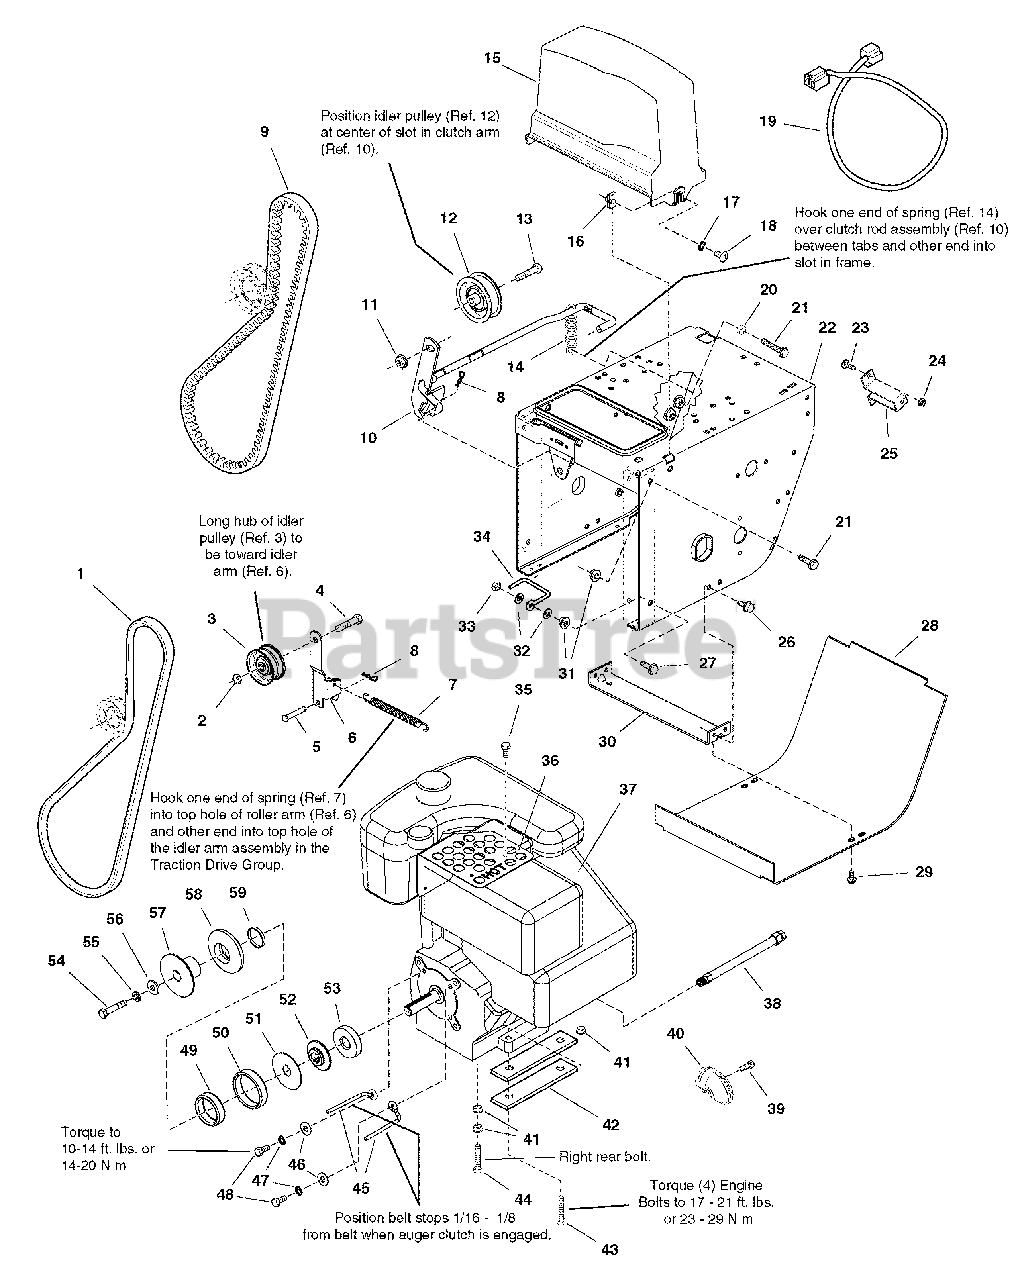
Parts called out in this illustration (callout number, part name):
1	V-BELT, 3L (Used Only on 38 in. Models)
2	NUT, Hex, Toplock, Jam, 3/8-16
3	PULLEY, Idler
4	CAPSCREW, Hex Head, 3/8-16 x 1-1/2
5	PIN, Flat Head Drilled
6	ARM, Idler, 5-3/4 LG
7	SPRING, Extension
8	PIN, Quick
9	V-BELT, HA (Used Only on 38 in. Models)
10	ROD AND ARM ASSEMBLY, Clutch Brake
11	NUT, Hex Flange, 3/8-16 Whiz Lock Large
12	PULLEY, Idler
13	CAPSCREW, Hex Whiz Lock Flange, 3/8-16 x 1-3/4
14	SPRING, Extension
15	COVER, Belt
16	NUT, Speed, 5/16-18, Lug Type
17	LOCKWASHER, External Tooth, 5/16
18	SCREW, Truss head Slotted, 5/16-18 x 3/4
19	CORD, Electric Extension
21	CAPSCREW, Hex Whiz Lock Flange, 5/16-18 x 3/4
22	FRAME ASSEMBLY, Chain/Tube Handles
23	CARRIAGE BOLT, 1/4-20 x 3/4 G5
24	NUT, Hex KEPS, 1/4-20, Conical Washer
25	SUPPORT, Clutch Cable, 16GA
26	CAPSCREW, Hex Washer Head Taptite, 5/16-18 x 3/4
27	CAPSCREW, Hex Whiz, 31/100-18 x 1-1/4
28	COVER, Bottom Frame, 20GA
29	CAPSCREW, Hex Washer Head Taptite, 1/4-20 x 1/2
30	SUPPORT, Tie Bar
31	NUT, Hex Flange, 5/16-18, Whiz Lock Large
32	WASHER, Flat, 11/32 x 3/4 x 1/16
33	NUT, Hex Centerlock, 5/16-18
35	CAPSCREW, Hex Washer Head Taptite, #10-24 x 1/2
36	GUARD, Muffler, 18GA
37	ENGINE, 10.5HP Briggs & Stratton Electric Start
37	ENGINE, 11.5HP Briggs & Stratton Electric Start
37	ENGINE, 13HP Briggs & Stratton Electric Start
38	HOSE, Oil Drain, w/Fittings
39	CAPSCREW, Muffler Deflector
40	DEFLECTOR, Rain Guard, B&S Snow Muffler
41	NUT, Hex Flange, 5/16-18, Whiz Lock Small
42	SUPPORT, Engine Riser (Used on all models Except 38 in. Models)
43	CAPSCREW, Hex Whiz Lock Flange, 5/16-18 x 2-1/4 (Used on all models Except 38 in. Models)
43	CAPSCREW, Hex Head, 5/16-18 x 1-1/2 G5 (Used Only on 38 in. Models)
44	CAPSCREW, Hex Head, 5/16-18 x 2-1/2 G5 (Used on all models Except 38 in. Models)
44	CAPSCREW, Hex Head 5/16-18 x 1-3/4 G5 (Used Only on 38 in. Models)
46	WASHER, 5/16
47	LOCKWASHER, Spring, 5/16
48	CAPSCREW, Hex Head, 5/16-24 x 3/4 G5
49	SPRING, Compression
50	SPRING, Compression
51	WASHER, Thrust
52	PULLEY HALF, Middle
53	PULLEY HALF, Inside
54	CAPSCREW, Hex Head, 3/8-24 x 1-1/2 G8
55	LOCKWASHER, Spring, 3/8
56	WASHER, 3/8
57	PULLEY HALF, Outside
58	PULLEY HALF, Middle
59	WICK, Felt, Oil
